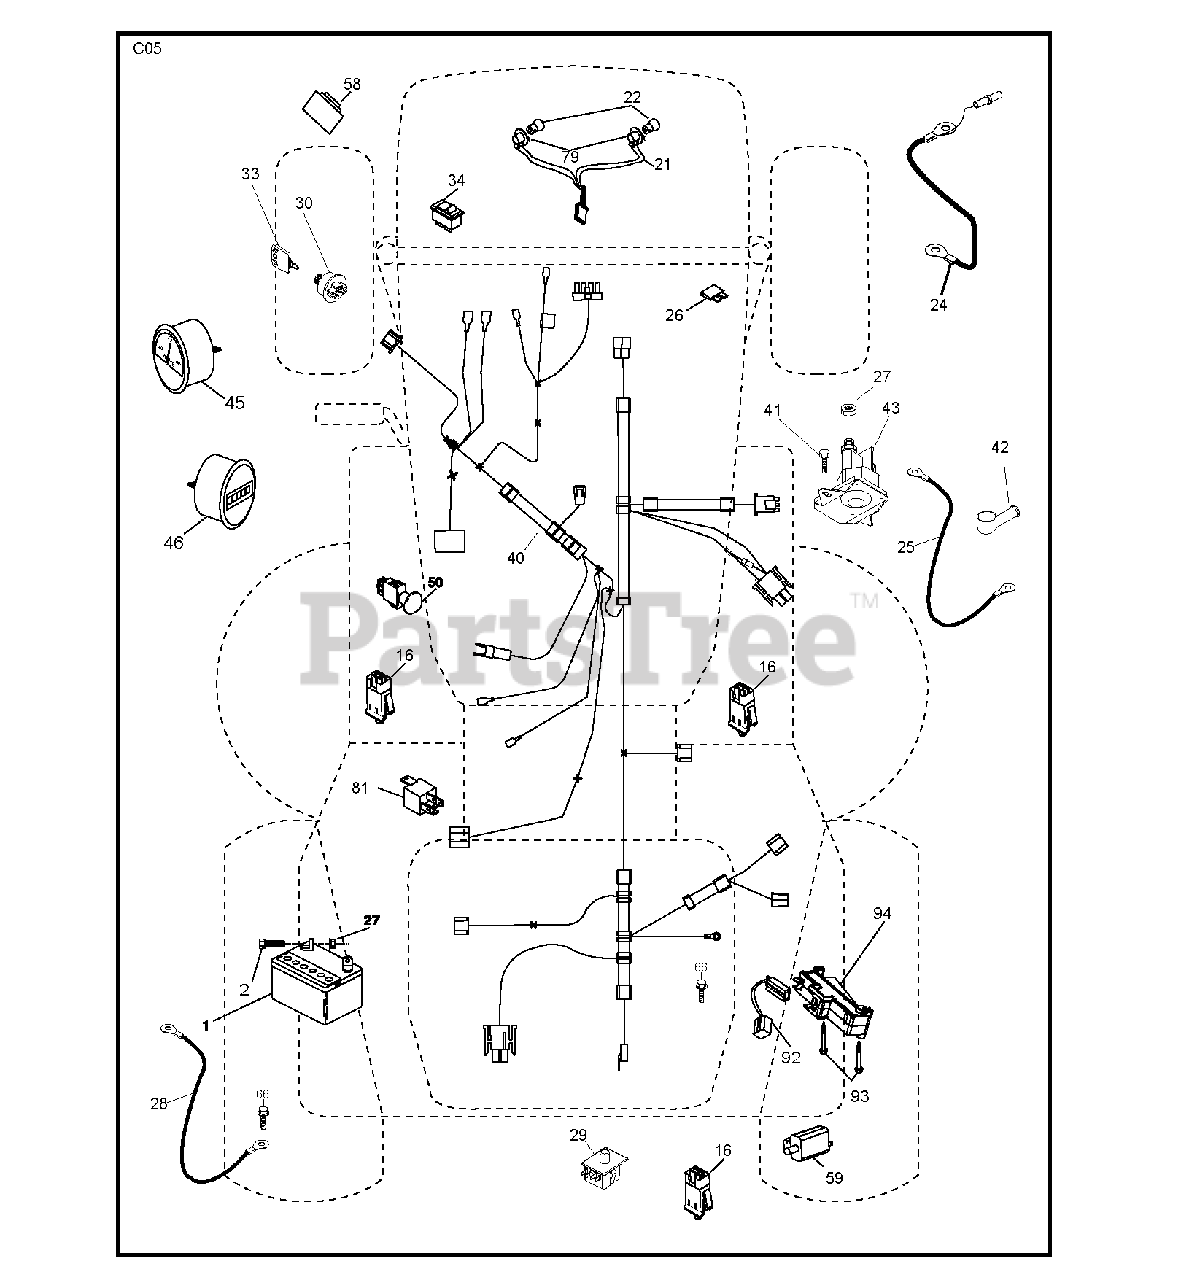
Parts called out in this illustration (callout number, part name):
1	REPL BY 532 12 38-99
16	SWITCH INTERLOOK PUSH-IN
21	HARNESS.W/LIGHT SOCKET
22	LIGHTBULB
24	CABLE BATTERY 6 GA. 11" RED
25	CABLE BATTERY
26	FUSE 20AMP
27	NUT
28	CABLE GROUND
29	SWITCH.SEAT.DP W/RAMPS
30	SWITCH.IGN.DELTA.W.LGH.ROS
33	KEY.CHAIN.BLISTER.PACK.GEN.INT
34	SWITCH LT
42	TERMINAL COVER
43	SOLENOID.W/BRASS.PLUNG
50	PTO SWITCH
58	BUZZER
79	BULB HOLDER ASM.
81	RELAY.ASSY.T
92	HARNESS.PIGTAIL.CONSLE
93	SCREW.PLASTITE
94	MODULE.REVERSE.ROS
